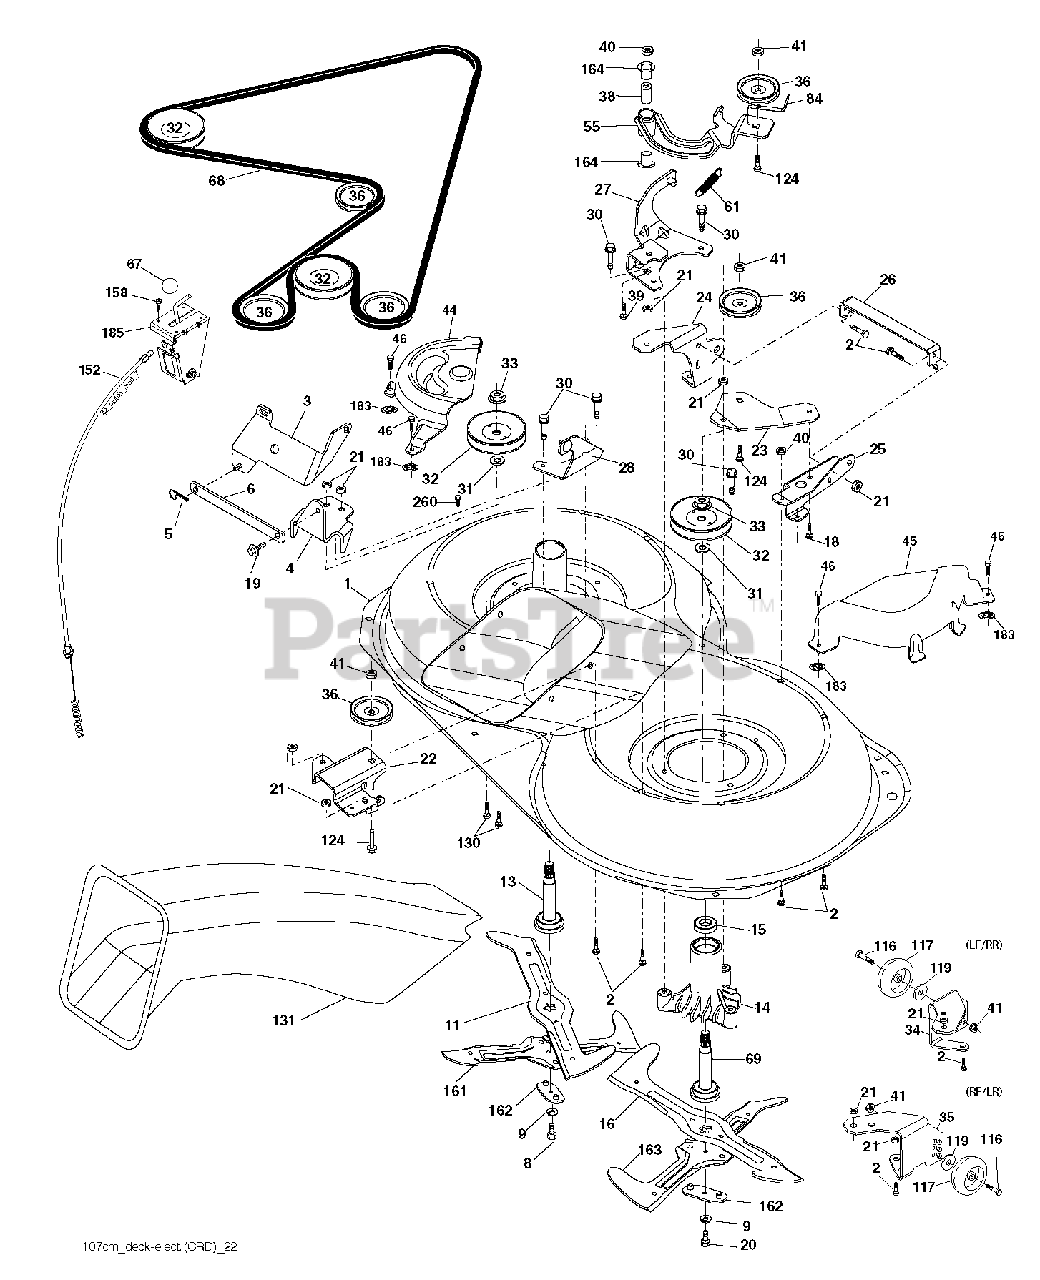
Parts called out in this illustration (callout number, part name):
2	BOLT
3	BRACKET.ASM.BAR.SWAY.CHASS
5	RETAINER-SPRNG RB
6	BAR SWAY
8	Bolt, 3/8-24 X 1.25 Gr8
9	LOCKWASHER
11	BLADE.3N1.LH.CRD
13	SHAFT ASM VENT
16	BLADE.3N1.RH.CRD
19	BOLT SHD 5/16-18
20	BOLT.3/8-24X1.25GR8. LHTHRD
21	LOCKNUT
22	BRACKET
23	BRACKET
27	BRACKET
30	SCREW, WASHER HEAD
31	WASHER.SPACER.MANDREL
33	NUT.FLANGE.LOCK.TOP
36	PULLEY.IDLER.4.25
40	LOCKNUT
41	NUT LOCK FLG 3/8-16 UNC
46	SCREW.1/4-20X5/8
67	KNOB T (3/8 HOLE)
68	HEX-BELT 107 MOWER
69	SHAFT.ASM.W/LWR.BRG.RH.THREAD
84	KEEPER, BELT IDLER
116	BOLT.SHOULDER.3/8-16X3-5/8
117	WHEEL. GUAGE RALLY
124	BOLT.3/8-16X1.50
158	SCREW
162	ADAPTER ADAPTER.CROSS
164	BRNG T
185	HEAD ASM. CABLE CLUTCH
260	SCREW 3/8-16X1/2
